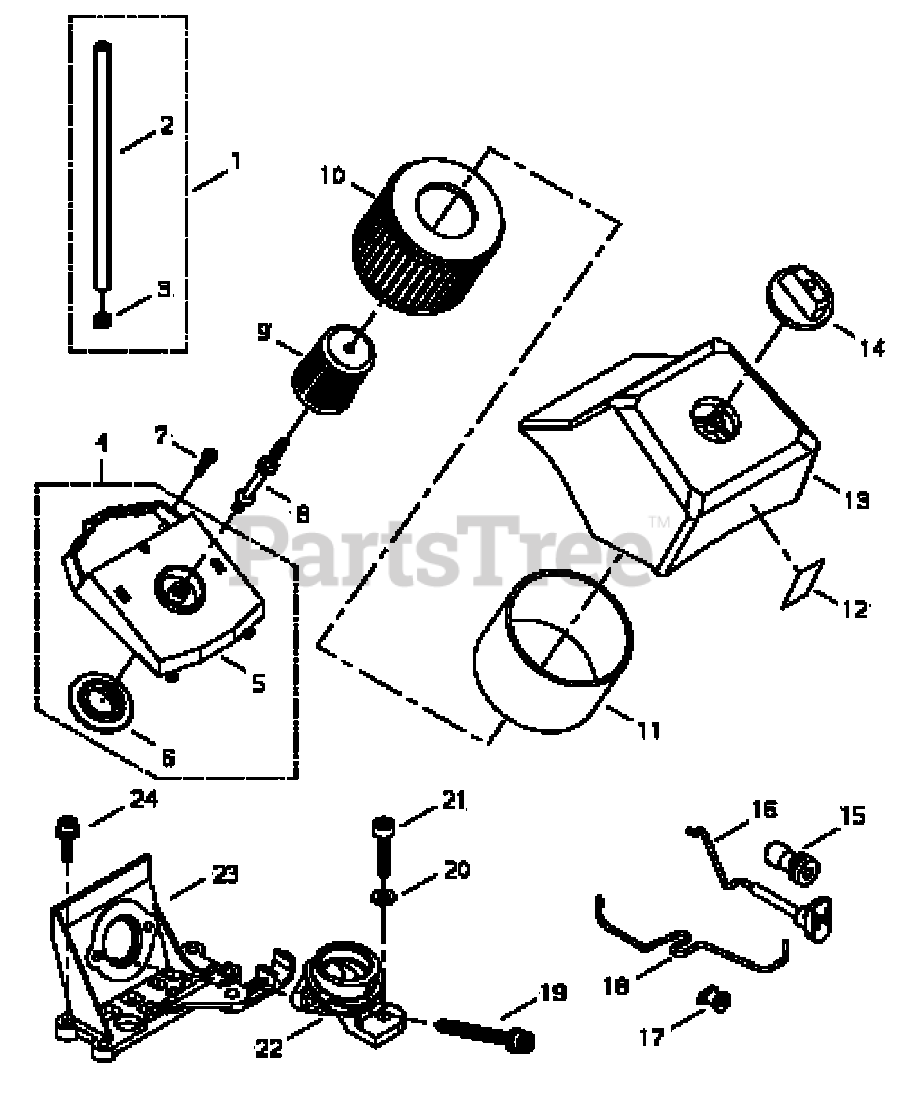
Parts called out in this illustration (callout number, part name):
1	PULSE PIPE ASSY
2	PIPE - PULSE
3	CLIP - 5.7
4	CLEANER BASE COMP
5	CASE, AIR FILTER
6	SEAL
7	SCREW - 5X16
8	BOLT
9	SUB FILTER
10	FILTER
11	PRE-FILTER -- FOAM
12	LABEL - CAUTION
13	CASE, AIR FILTER
14	THUMBSCREW
15	GROMMET
16	ROD, CHOKE
17	GROMMET
18	ROD, THROTTLE
19	BOLT
20	WASHER - 5
21	BOLT
22	ADAPTOR, INTAKE
23	BRACKET, AIR CLEANER
24	SCREW - 4X16
